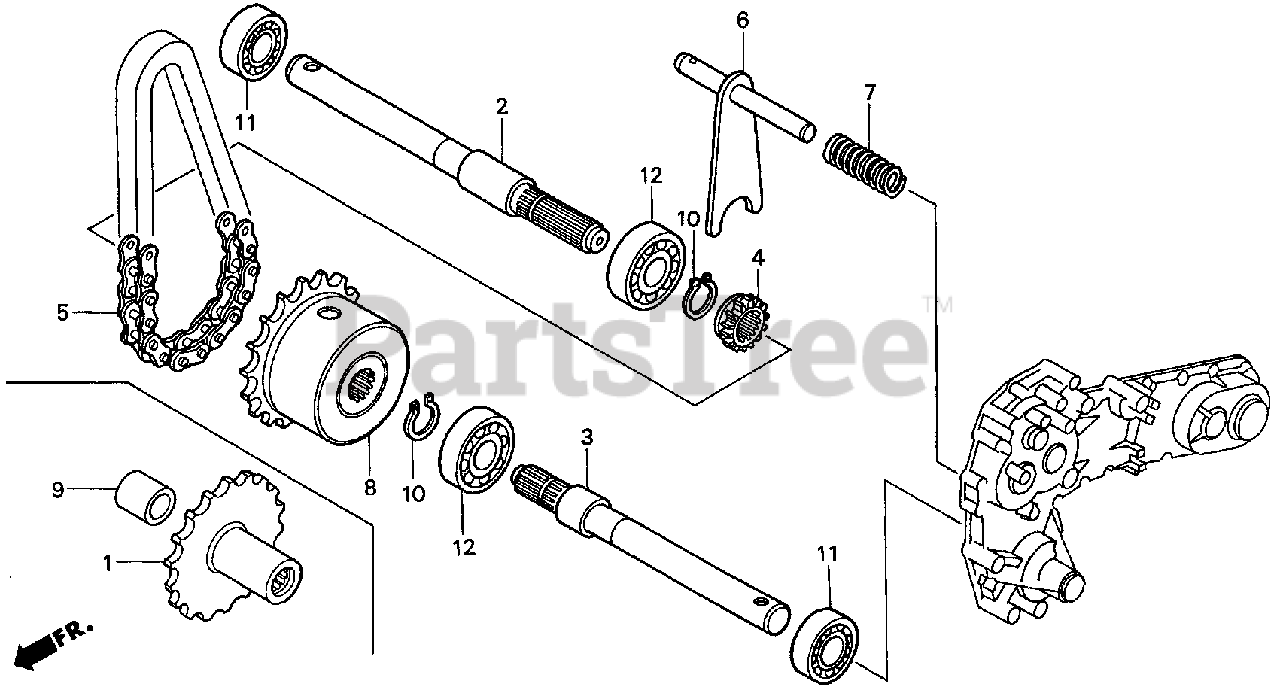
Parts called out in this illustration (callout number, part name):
2	SHAFT, R. WHEEL
3	SHAFT, L. WHEEL
4	GEAR, DIFFERENTIAL LOCK
5	CHAIN, FINAL
6	SHAFT, SHIFT
7	SPRING, DIFFERENTIAL LOCK FORK
8	DIFFERENTIAL ASSY.
10	CIRCLIP, OUTER (20MM)
11	BEARING, RADIAL BALL (6004)
12	BEARING, RADIAL BALL (6304)
